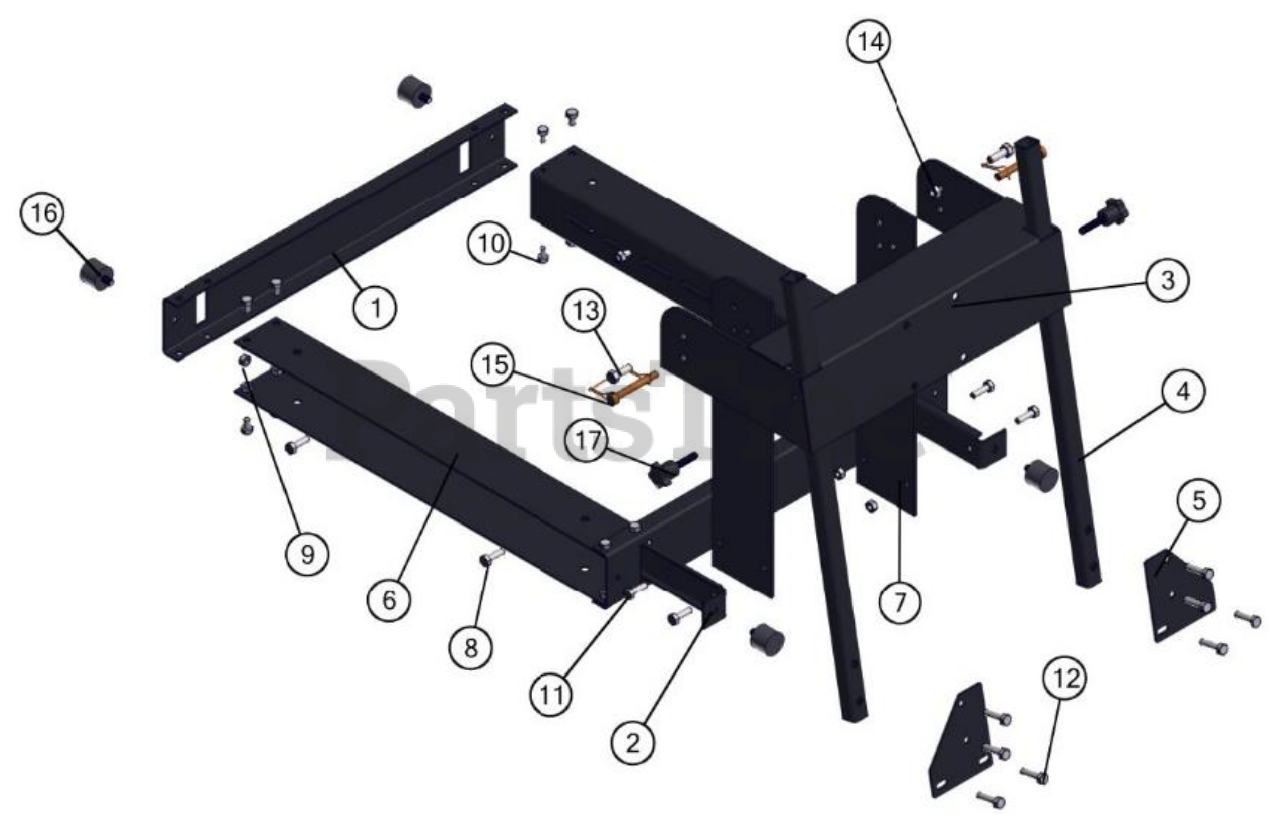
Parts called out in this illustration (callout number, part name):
1	CROSS BRACE FRAME
2	FRAME STABILIZER
3	FRAME TAILGATE
4	FRAME BOOM TUBE
5	FRAME BOOM BRACKET
6	FRAME SIDE RAIL
7	FRAME TAILGATE BRACKET
8	CARRIAGE BOLT 5/16-18X1
9	SERRATED FLANGE NUT 5/16-19
10	BOLT 5/16-18X1/2"
11	BOLT 5/16-18X1"
12	BOLT 5/16-18X1.75"
13	BOLT 3/8-16X1"
14	NYLON NUT 3/8"
15	PTO ADAPTER LOCK PIN
16	CYLINDRICAL MOUNT
17	BLACK "T" THUMB SCREW
